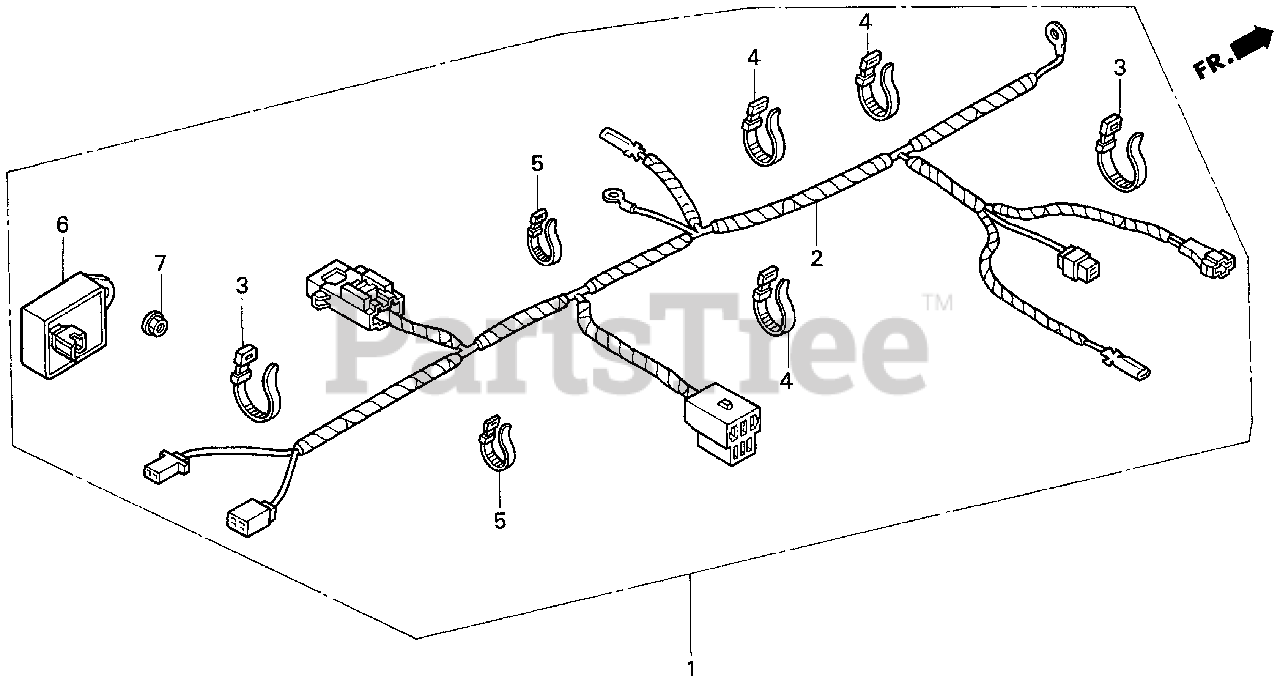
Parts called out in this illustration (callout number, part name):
1	KIT, COLD START Use up to Frame SN 1001879.
2	SUB-WIRE HARNESS Use up to Frame SN 1001879.
3	BAND, WIRE Use up to Frame SN 1001879.
4	BAND B1, CABLE Use up to Frame SN 1001879.
5	BAND B1, CABLE Use up to Frame SN 1001879.
6	CONTROL UNIT, GLOW Use up to Frame SN 1001879.
7	NUT, FLANGE (6MM) Use up to Frame SN 1001879.
